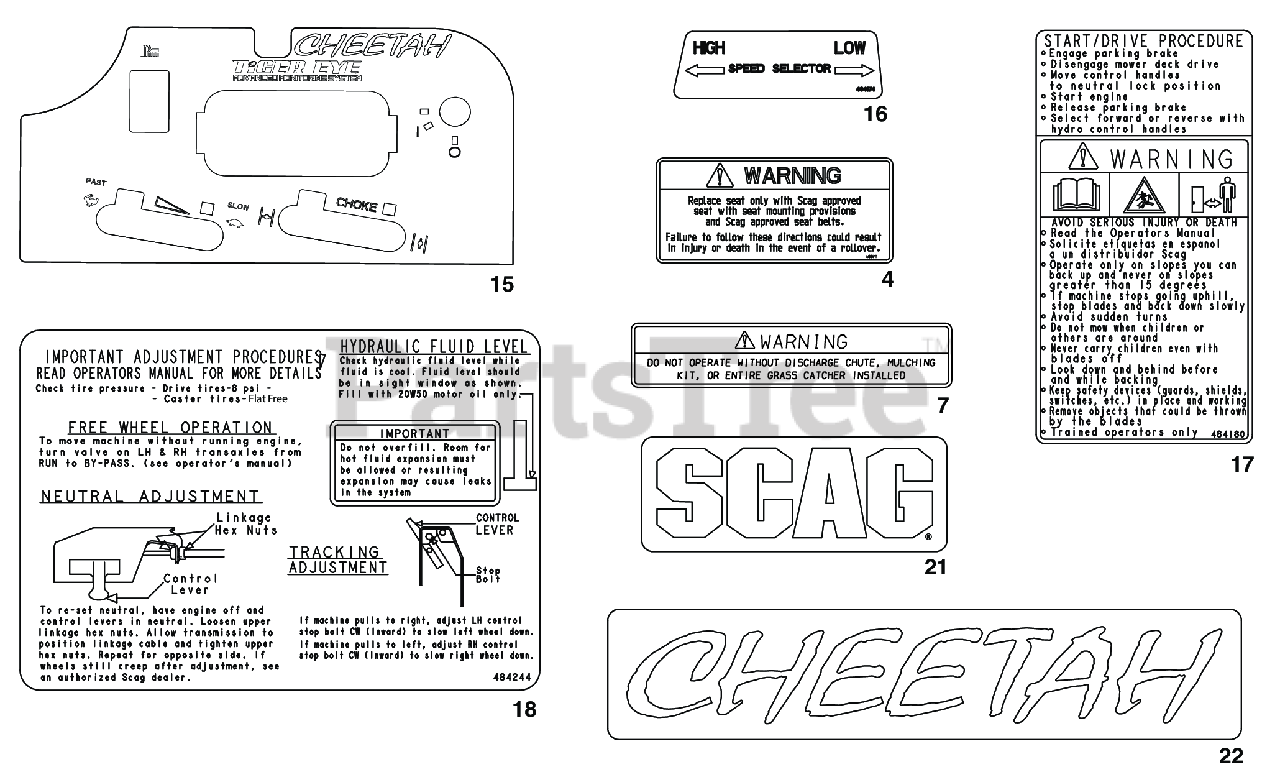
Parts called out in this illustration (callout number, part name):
4	Decal, Seat Replacement
7	Decal, Warning-Discharge
15	Decal, Instrument Panel - SCZ
15	Decal, Instrument Panel - SCZ - EFI
16	Decal, Speed Control
17	Decal, Start / Drive
18	Decal, Adjustments - SCZ
21	Decal, Scag - Fuel Tank
22	Decal, Cheetah - Fuel Tank
